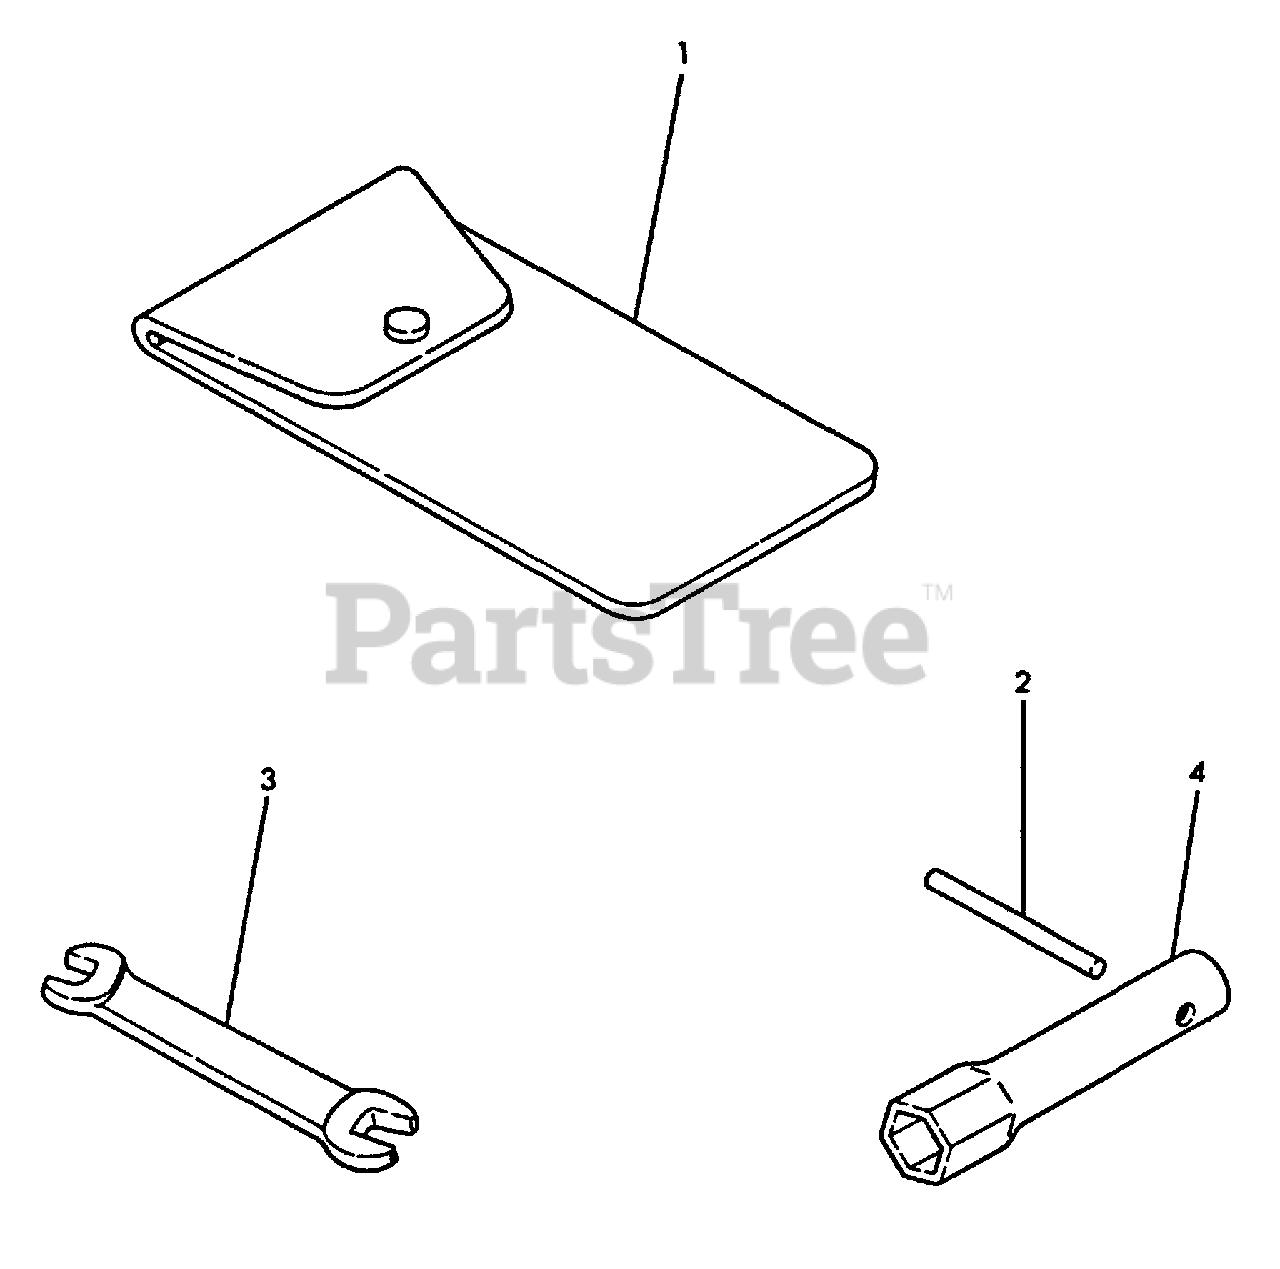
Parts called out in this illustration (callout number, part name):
1	BAG, TOOL
2	BAR
3	SPANNER - 10X12mm
4	SOCKET WRENCH - 14X19mm
